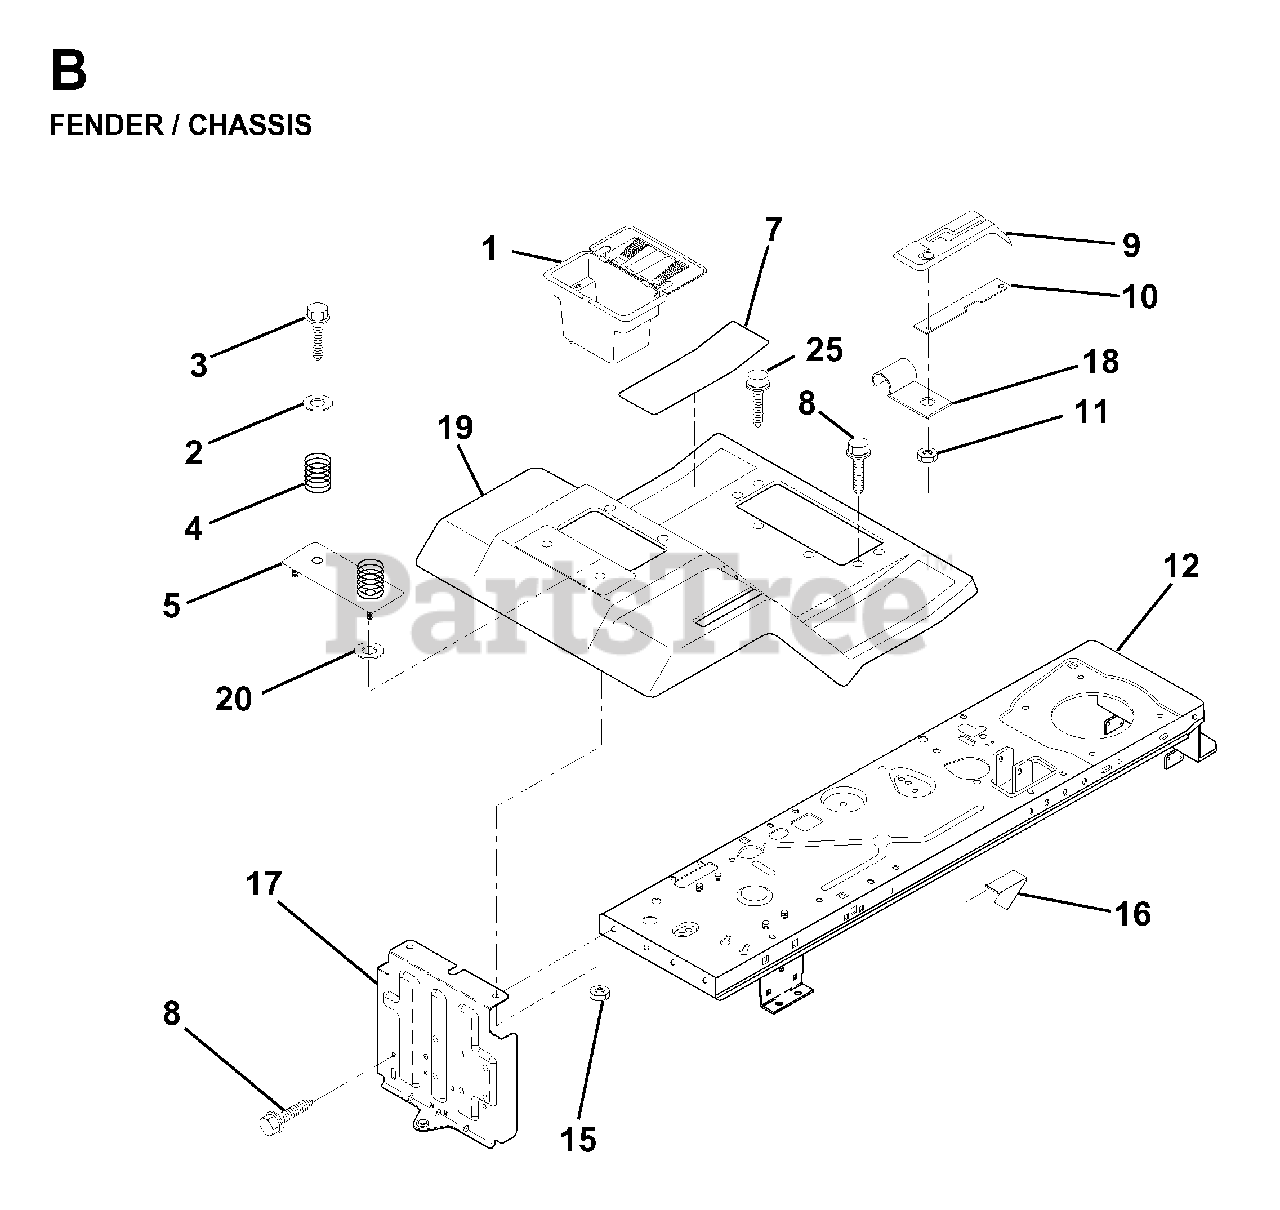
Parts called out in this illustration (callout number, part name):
1	CASE BATTERY MECH HINGE
3	SCREW
4	SPRING COMPRESSION
7	PAD FOOTREST
8	SCREW
9	CONSOLE SHT CONTR
10	BAR, SHIFT LOCK
18	CLIP,INSULATOR
20	WASHER
